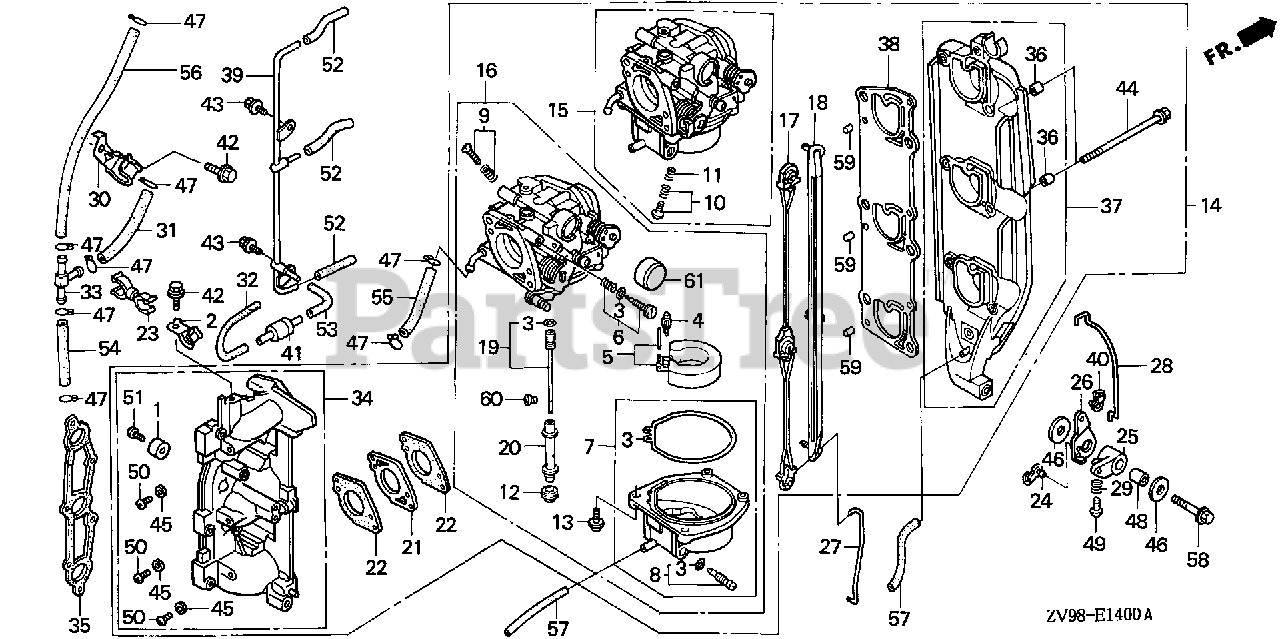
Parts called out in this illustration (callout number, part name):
1	METAL, ANODE
2	CLAMP, TUBE
3	GASKET SET
4	VALVE SET, FLOAT
7	CHAMBER SET, FLOAT
8	SCREW SET, DRAIN
11	SPRING, COMPRESSION COIL
12	SCREW, PLUG
13	SCREW-WASHER
14	CARBURETOR ASSY. (BG10B B) *NH8* (DARK GRAY)
14	CARBURETOR ASSY. (BG10B C) *NH8* (DARK GRAY)
15	CARBURETOR ASSY. (#1/#2) (CARBURETOR NO.)
16	CARBURETOR ASSY. (#3) (CARBURETOR NO.)
17	LEVER, LINK
18	LINE, CHOKE
19	JET SET (#38)
20	NOZZLE, MAIN
21	INSULATOR, CARBURETOR
22	GASKET, CARBURETOR
23	CLAMP, FUEL TUBE (A)
24	JOINT, ROD
25	ARM A, CHOKE
26	ARM B, CHOKE
27	ROD, CHOKE
28	ROD, CHOKE KNOB
29	SPRING, CHOKE ARM ADJUSTING
30	CLAMP, FUEL TUBE
31	TUBE C, FUEL
32	TUBE D, FUEL
33	PIPE, THREE WAY JOINT
34	MANIFOLD ASSY., IN. *NH8* (DARK GRAY)
35	GASKET, IN. MANIFOLD
36	COLLAR, DISTANCE (6.5X11X7.5)
36	COLLAR, DISTANCE
37	PLATE, MUFFLER
38	GASKET, MUFFLER PLATE
39	PIPE, INSTALL
40	BUSH, LINKAGE
41	VALVE, DASHPOT CHECK
42	BOLT, FLANGE (6X12)
42	BOLT, FLANGE (6X12) (CT200)
43	BOLT, FLANGE (5X10)
44	BOLT, FLANGE (6X97)
45	WASHER, SEALING (5MM)
46	WASHER, PLAIN (6MM)
47	CLIP, TUBE (B10)
48	COLLAR, DISTANCE (6.5X10.5X16)
49	SCREW, PAN (4X16)
50	SCREW, PAN (5X10)
51	SCREW, PAN (6X18)
52	BULK HOSE, FUEL (3.5X3000) (3.5X45)
53	BULK HOSE, FUEL (3.5X3000) (3.5X65)
54	BULK HOSE, FUEL (5.5X3000) (5.3X55)
55	BULK HOSE, FUEL (5.5X3000) (5.3X70)
56	BULK HOSE, FUEL (5.5X3000) (5.3X175)
57	BULK HOSE, VINYL (3.5X6.5X8000) (9500(95003-05001-60M)
58	BOLT, FLANGE (6X28)
59	ROLLER (6X15)
60	JET, MAIN (#95)
60	JET, MAIN (#98)
60	JET, MAIN (#100)
61	CAP, CHOKE DUST
